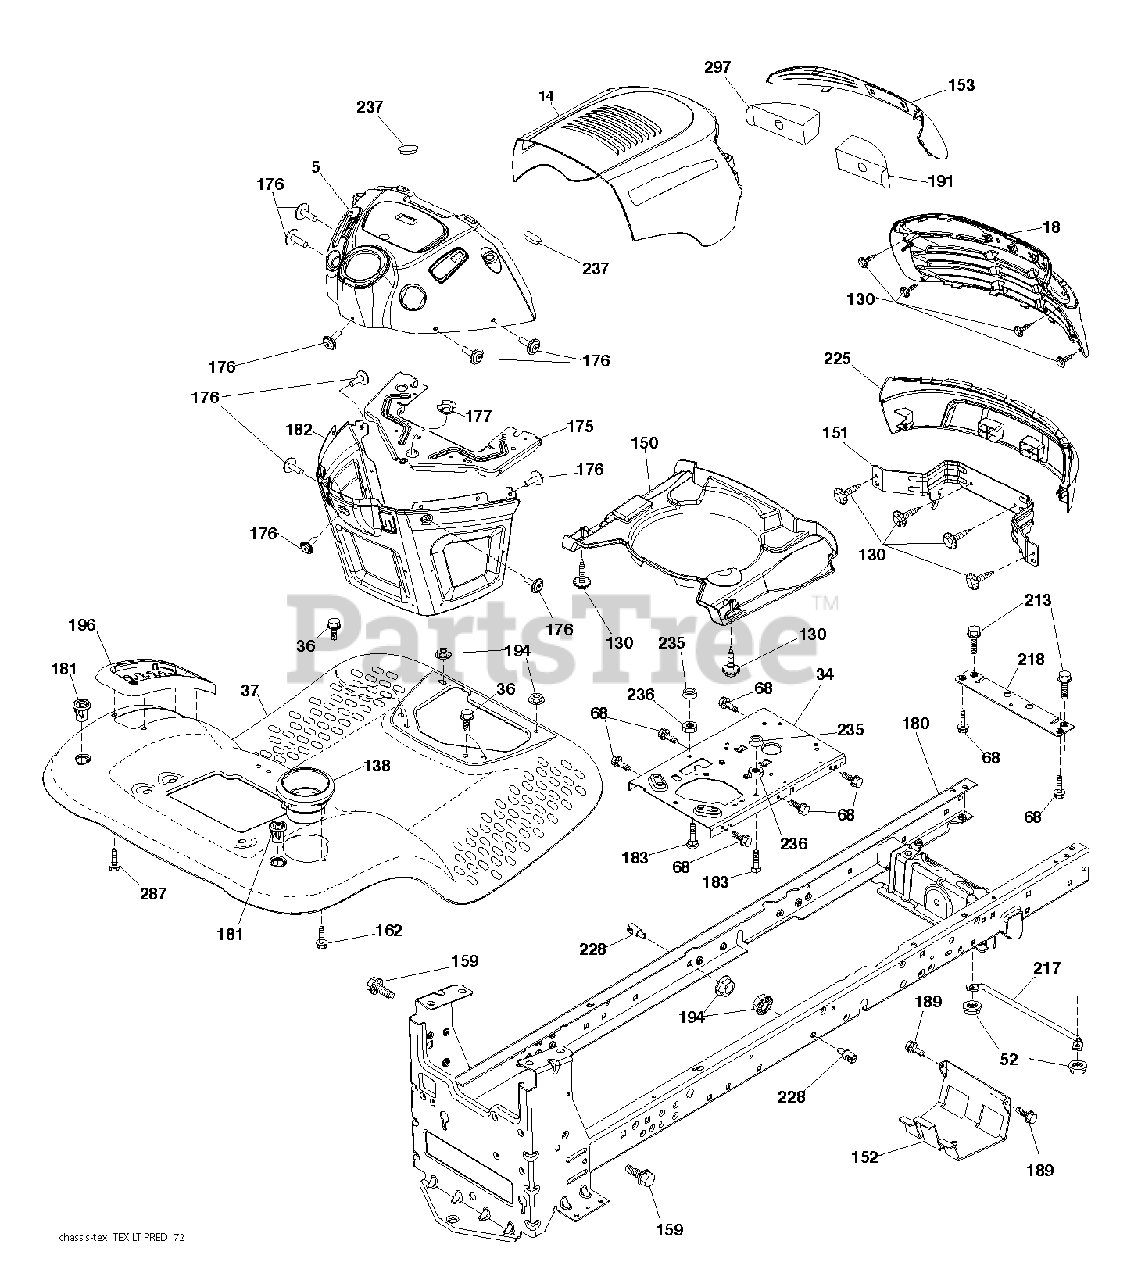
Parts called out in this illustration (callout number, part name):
68	SCREW LT
130	SCREW.#10 X 0.750.BOS THREAD
138	CUPHOLDER
152	SHIELD BROWNING
159	SCREW, 3/8-16X3/4
162	SCREW,HEX
176	SCREW.#10-24X5/8.RN.QU
180	CHASSIS
181	FEND/FTRST.PCH.CPH.NFW
183	BOLT.5/16-18X1-1/4 FULL THD
189	SCREW
194	NUT LOCK HEX FLANGE 5/16-18
196	CONSOLE ASM. DECK LIFT
228	STUD.FASTNER.W/D.ANTI-
235	SPACER FENDER
236	JAM LOCK NUT
